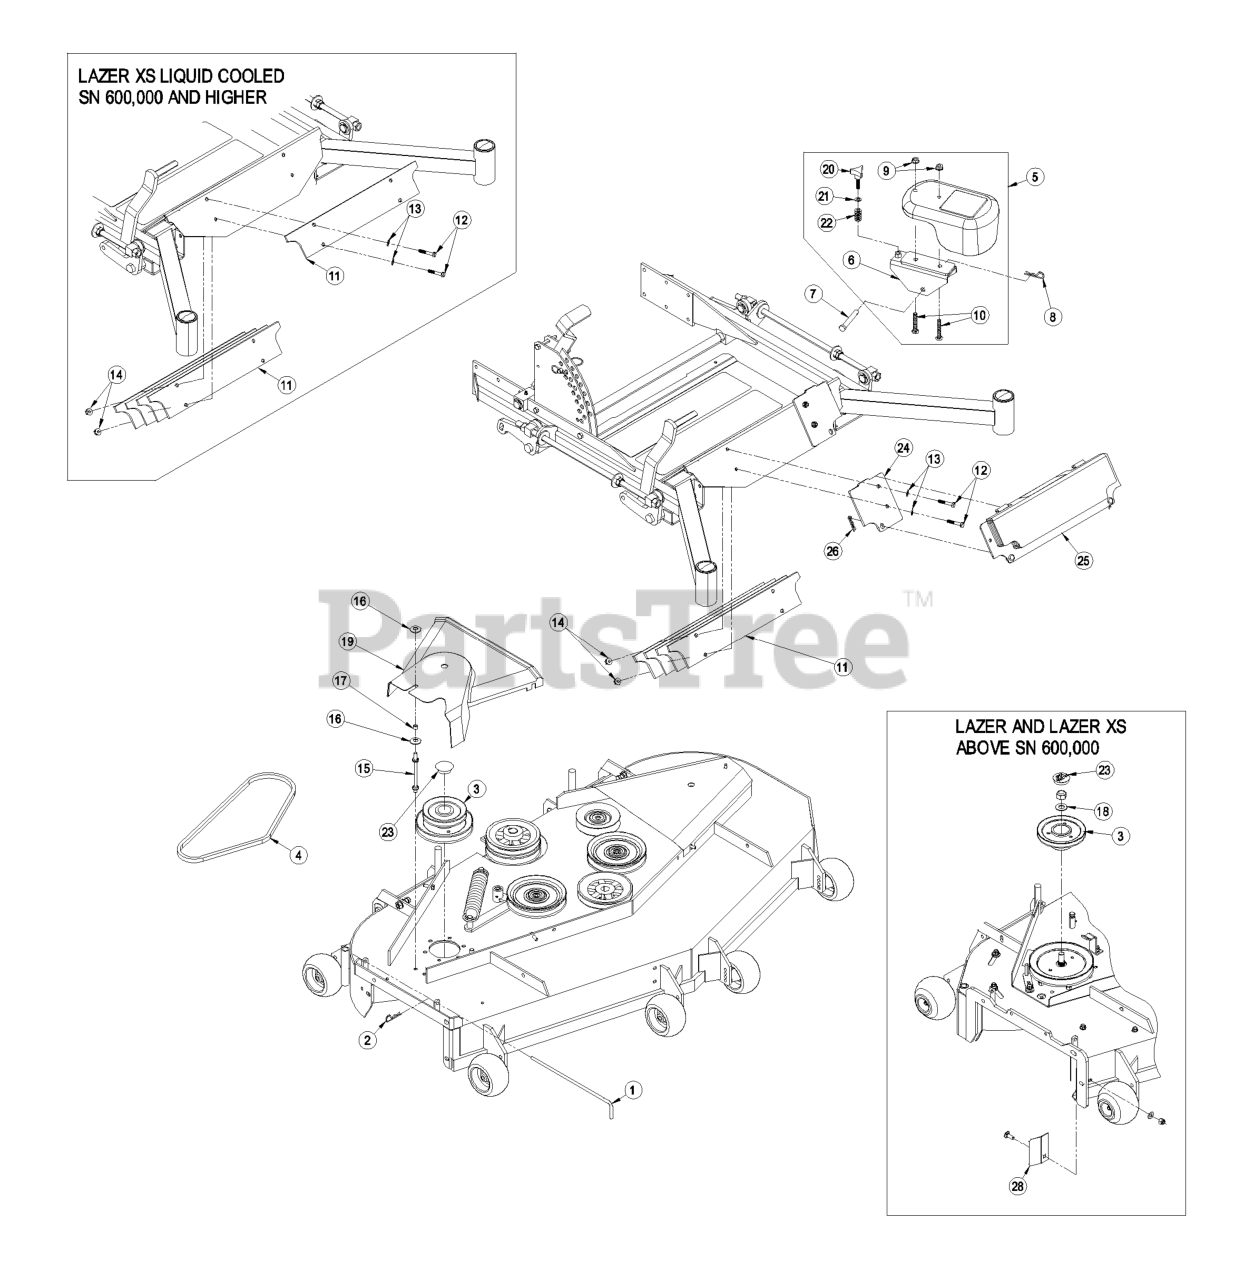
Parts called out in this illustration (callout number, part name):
1	PIN,CHUTE PIVOT
2	PIN-COTTER
3	JACKSHAFT, LZUV72
4	BELT, BLOWER DRIVE 72
5	ASM, WEIGHT 2.0" 43 POUND
6	WLD, BRACKET 2.0 ARM
7	PIN-CLEVIS
8	PIN-COTTER
9	NUT-HHF, WHIZ
10	BOLT-SQH
11	PLATE, WEIGHT
12	SCREW-HH
13	WASHER-PLAIN
15	STUD,BELT SHIELD 4 INCH
17	Spacer, Grommet
18	Washer, 5/8 SAE
19	COVER, BELT 72
21	WASHER-FLAT
23	PLUG, BLACK NYLON 1.75
24	PLATE, WEIGHT MOUNTING
25	ASM, WEIGHT PLATE WITH DE
26	PIN-HAIR
28	Deflector
